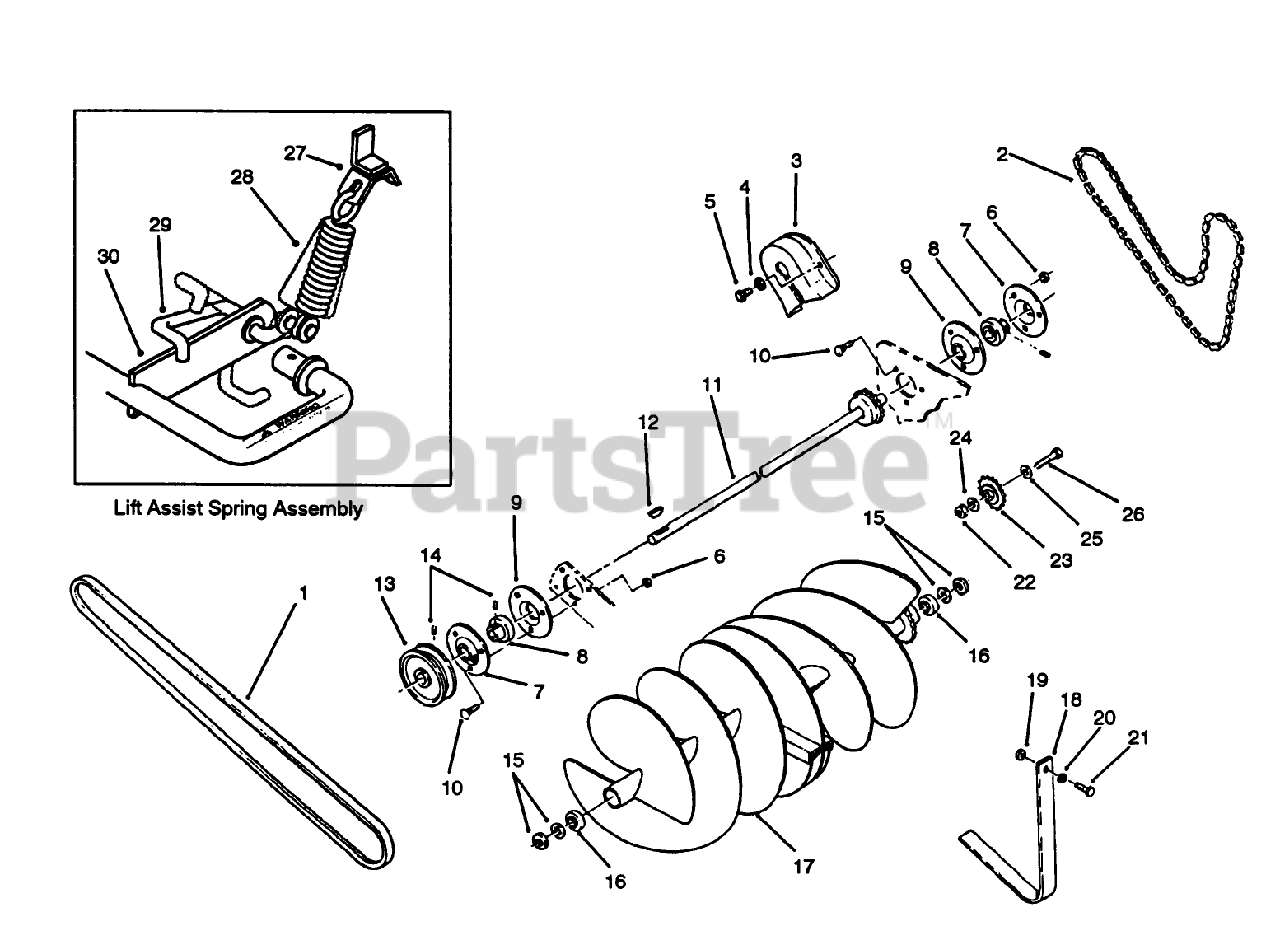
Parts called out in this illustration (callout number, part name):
1	Belt
2	CHAIN-64 PITCHES
3	GUARD-CHAIN
4	WASHER-FLAT
5	SCREW-HWH
6	NUT-LOCK, NI
7	FLANGE-ZERK RELUBE
8	BEARING AND COLLAR
9	Flange
10	BOLT-CARR
11	Shaft Assembly
12	Key
13	PULLEY
14	SCREW-SQH
15	WASHER-FLAT
16	BEARING-BALL
17	Auger
18	Guard-Outer
19	NUT-KEPS
20	WASHER-FLAT
21	SCREW-HH
22	NUT-LOCK, NI
23	Idler Sprocket
24	WASHER-FLAT
25	SPACER
26	SCREW-HH
27	BRACKET
28	Spring
29	Rod
30	Shaft
